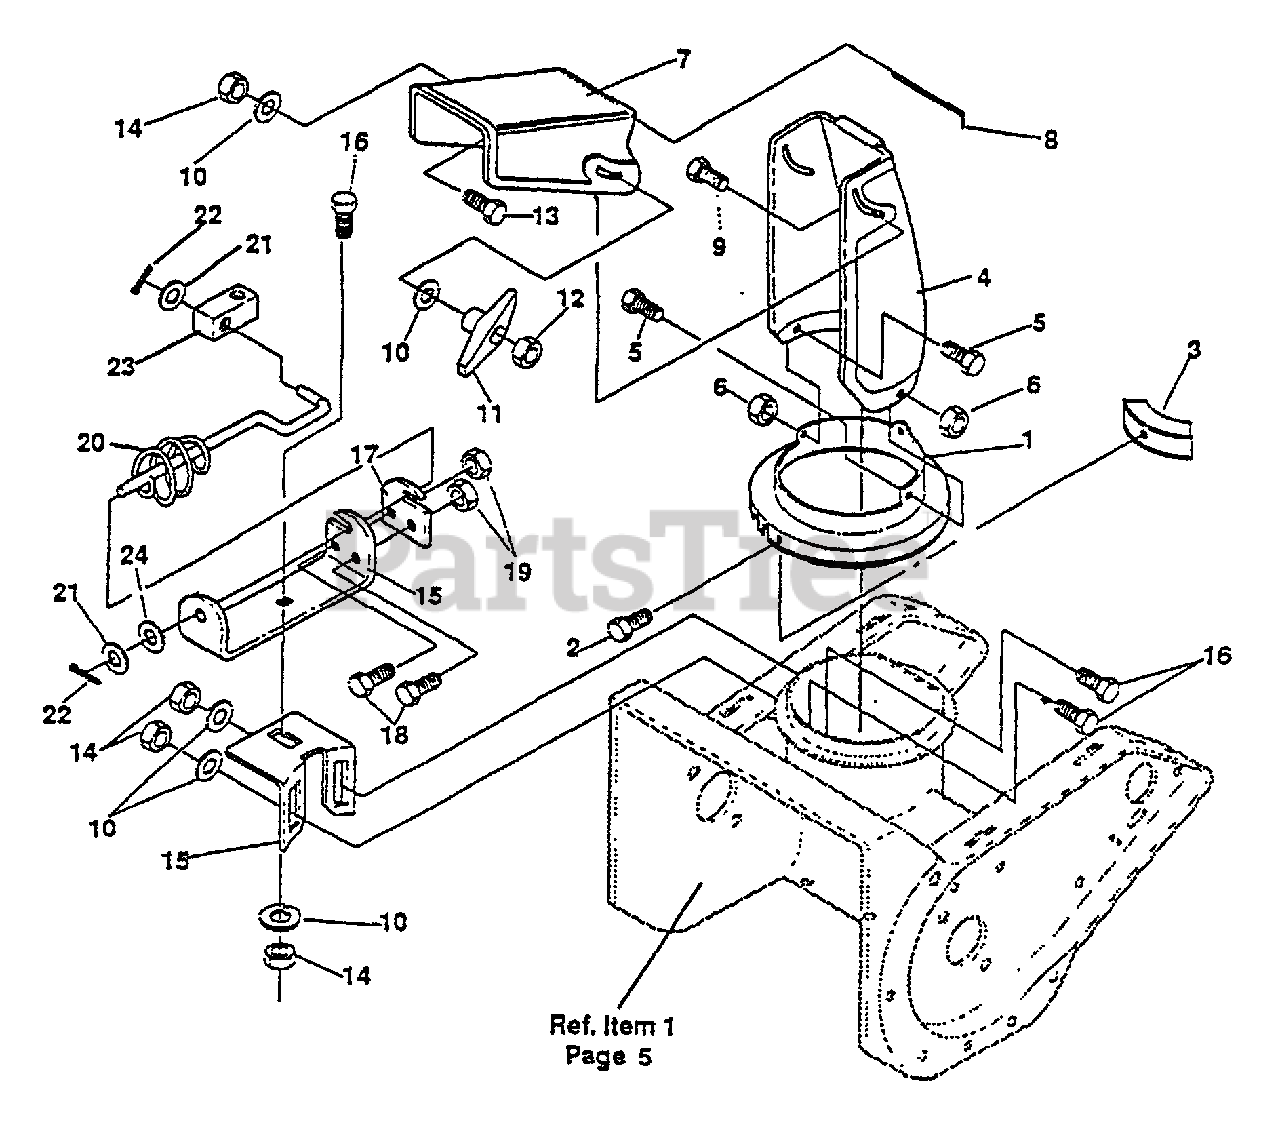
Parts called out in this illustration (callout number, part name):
1	RING, LWR CHUTE
2	SCREW 1/4"-14×0.63
3	CLIP, CHUTE RING PLASTIC
4	CHUTE - LOWER
5	SCREW 1/4"-20×0.50
6	NUT - 1/4-20
7	CHUTE - UPPER
8	WIRE, CHUTE HINGE
9	BOLT 5/16"-18×1.25" CARRLN
10	WASHER
11	KNOB, T 2 BLADE W/5/16-18 NUT
13	SCREW 5/16"-18×0.75
14	NUT, 5/16"-18
15	BRACKET, WORM ADJUST
15	BRACKET, CHUTE ROD
16	BOLT, CARRIAGE 5/16-18×0.75
17	PLATE, CHUTE ROD
18	SCREW 1/4"-20×0.50
19	NUT, 1/4"-20
20	ROD ASSY, CHUTE CONTROL LOWER
21	WASHER, FLAT 0.390×0.75×0.031
22	PIN - COTTER
23	BLOCK, PIVOT PLASTIC
24	WASHER, SADDLE
